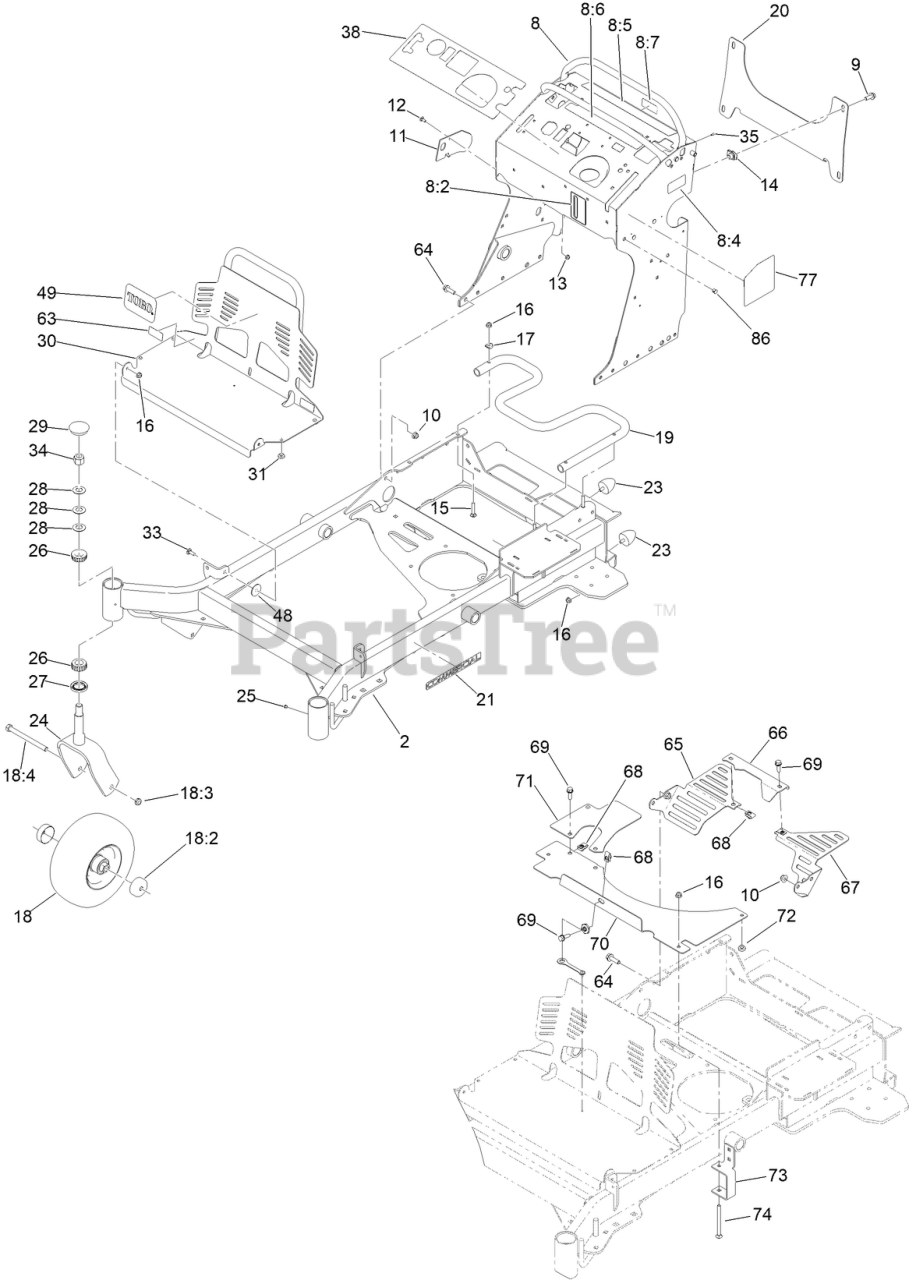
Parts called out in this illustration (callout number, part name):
8	TOWER ASM
8:2	DECAL-LEVEL, OIL
8:4	DECAL-FILL, FUEL
8:5	DECAL-WARNING
8:6	DECAL-CONTROLS
8:7	DECAL-FUSE
9	SCREW-HHF
10	NUT-HF, NI
11	PLATE-STRIKER
12	SCREW-CARR
13	NUT-HF
14	NUT-TINNERMAN
15	BOLT-CAR
16	NUT-HF, NI
17	WASHER
18	MF WHEEL TIRE BEARING ASM
18:2	GUARD-SEAL
18:3	NUT-HEX
18:4	SCREW-HH
19	TUBE-MOUNT, FUEL TANK
20	BRACKET-CROSS
21	DECAL-COMMERCIAL
23	BUMPER-RUBBER
24	FORK-CASTER
26	BEARING-ROLLER, TAPERED
27	SEAL-GREASE
28	WASHER-BELLVILLE
29	CAP-GREASE
30	GUARD-ENGINE
31	BUMPER
33	BOLT-CARR
34	NUT-LOCK, NI
35	RIVET-POP
38	DECAL-PANEL, CONTROL
48	WASHER-NYLON
63	DECAL-WARNING, NO RIDERS
64	SCREW-HHF
65	GUARD-FAN, RH (CE)
66	GUARD-FAN, CENTER (CE)
67	GUARD-FAN, LH (CE)
68	NUT-U
69	SCREW-HHF
70	GUARD-EXTENSION
71	GUARD-BELT, CE
72	BUMPER
73	BRACKET-MOUNTING, GUARD
74	SCREW-CARR
77	DECAL - SERVICE RD, CE
86	DOME PANEL PLUG
